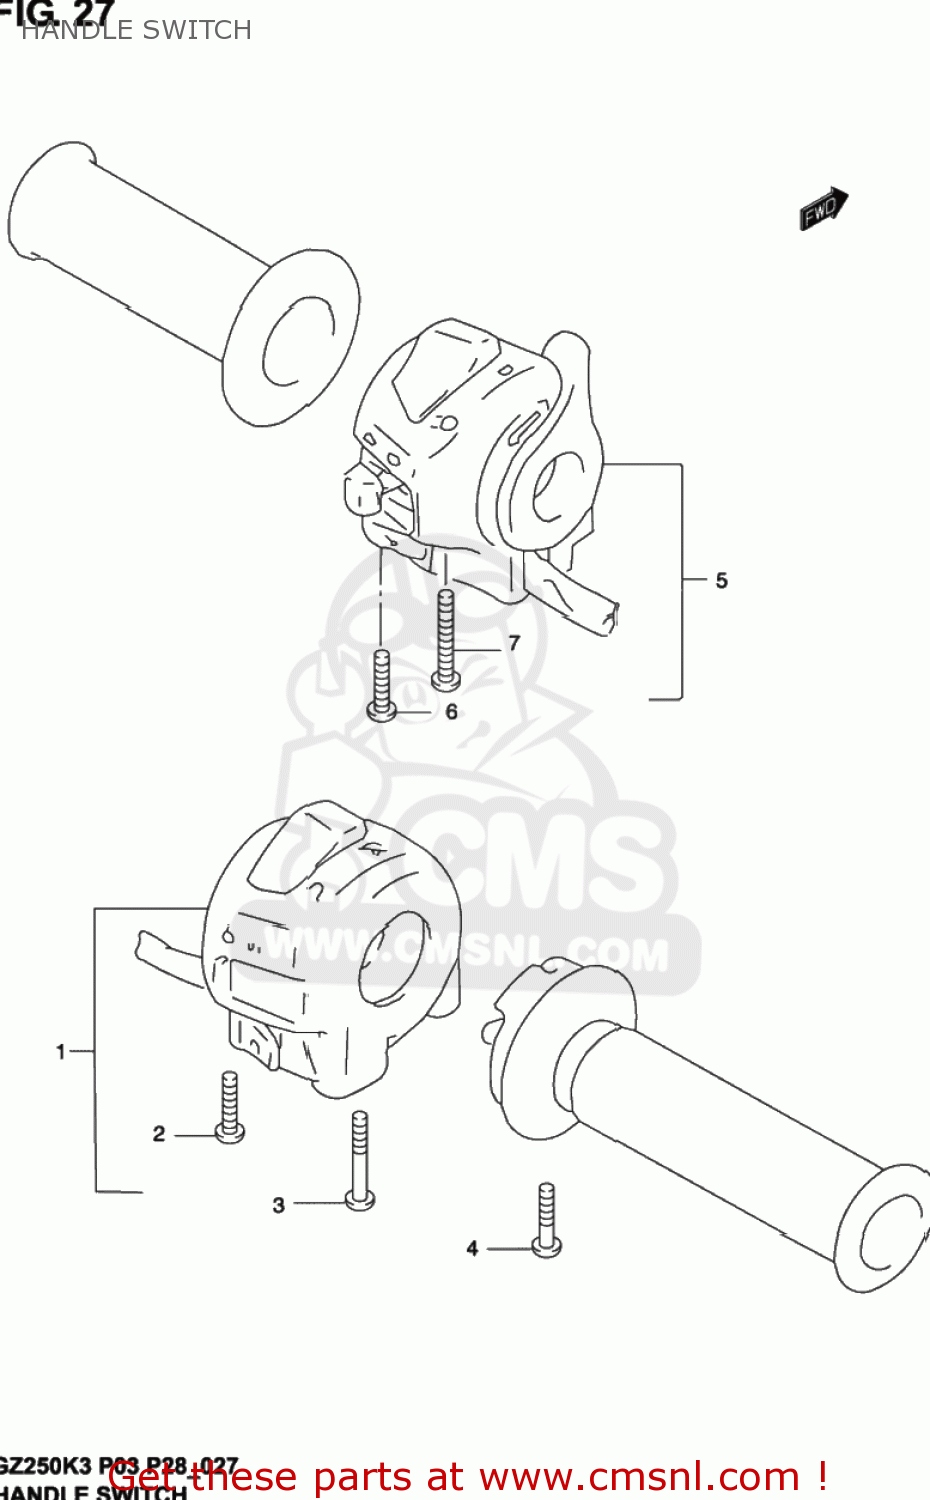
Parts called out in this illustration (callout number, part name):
1	SWITCH ASSY RH
2	SCREW
3	SCREW
4	SCREW
5	SWITCH ASSY, HANDLE LH
6	SCREW
7	SCREW
